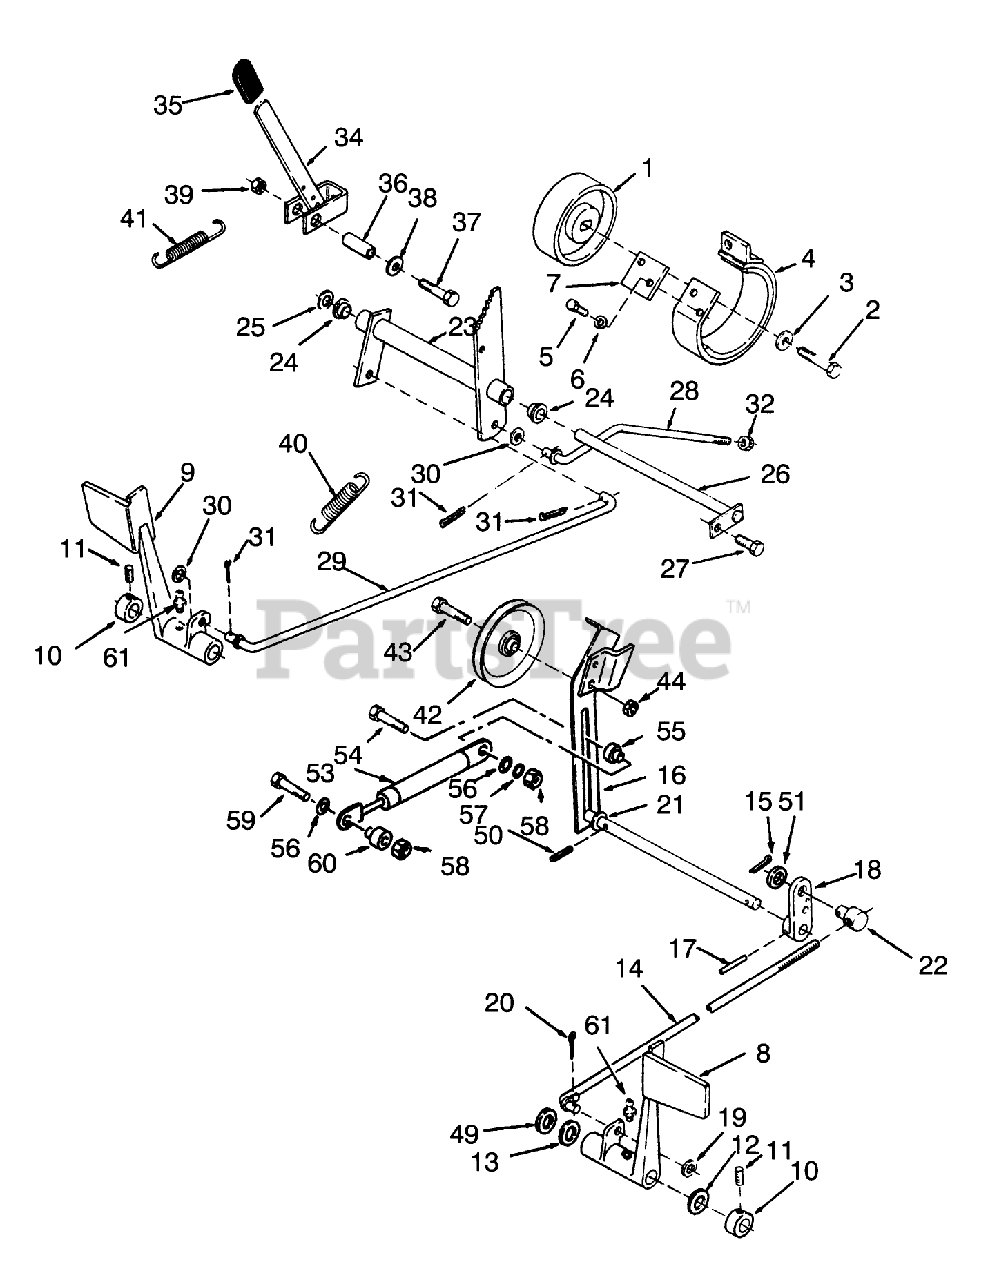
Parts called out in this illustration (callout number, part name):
1	DRUM-BRAKE
2	SCREW-HEX HD CAP
3	WASHER
4	BRAKE BAND ASM
5	SCREW-HH
6	WASHER-LOCK
7	Plate-Stop
8	PEDAL-CLUTCH R
9	Pedal-Brake
10	COLLAR
11	SCREW-HSH
12	WASHER-BOWED
13	WASHER
14	ROD AND GUIDE ASM
15	PIN-COTTER
16	Arm-Clutch Idler
17	PIN-SPIROL
18	Arm-Clutch Rod
19	WASHER-NYLON
20	PIN-COTTER
21	SHIM-WASHER
22	TRUNNION
23	Bellcrank Assy
24	BUSHING-FLANGED
25	WASHER-FLAT
26	ROD ASM
27	Bolt
28	ROD-REAR BRAKE
30	WASHER-NYLON
31	PIN-COTTER
32	NUT-LOCK, NI
34	ASSY-BRAKE LEVER WAB
35	GRIP
36	SPACER
37	SCREW-HH
38	WASHER-FLAT
39	LOCKNUT-FLANGE
40	SPRING-BRAKE
41	SPRING-EXTENSION
42	PULLEY-IDLER
43	BOLT-SPECIAL HEX
44	NUT-LOCK, NI
49	WASHER
50	PIN-SPIROL
51	WASHER-FLAT
53	ASS'Y-GAS SPRING
54	SCREW-HH
55	SPACER-SHOULDER-.200
56	WASHER-FLAT
57	WASHER-LOCK
58	NUT-LOCK, NI
59	SCREW-HH
60	SPACER-SHOULDER-.400
61	FITTING-GREASE
